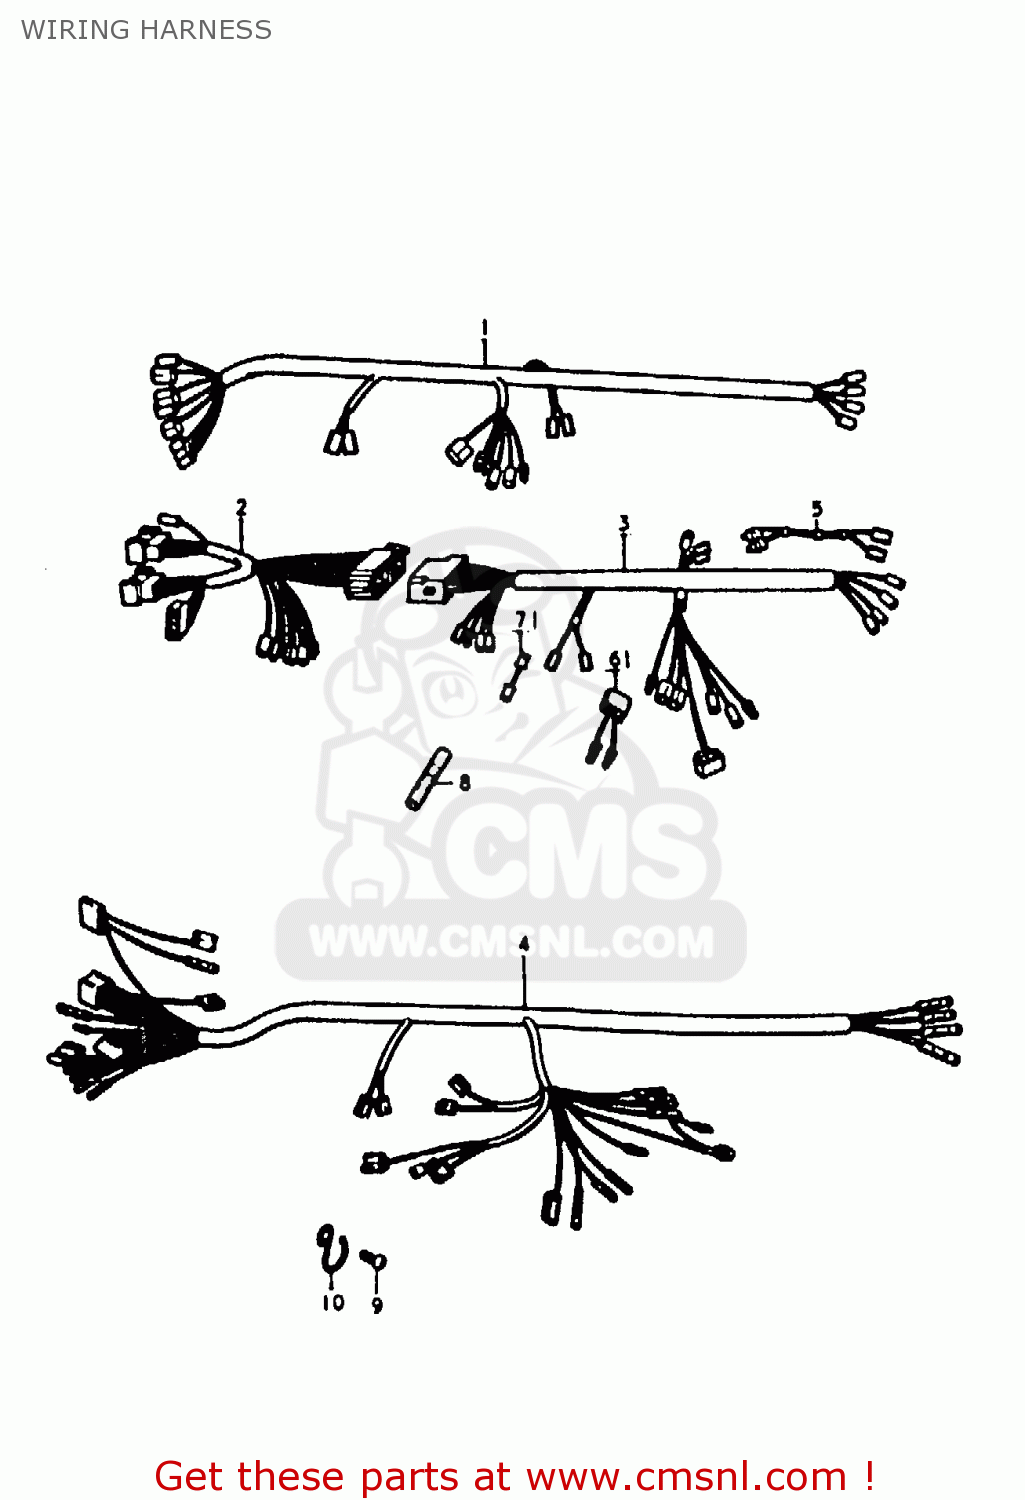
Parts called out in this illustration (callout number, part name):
4	WIRING HARNESS
9	CLIP
10	SCREW
